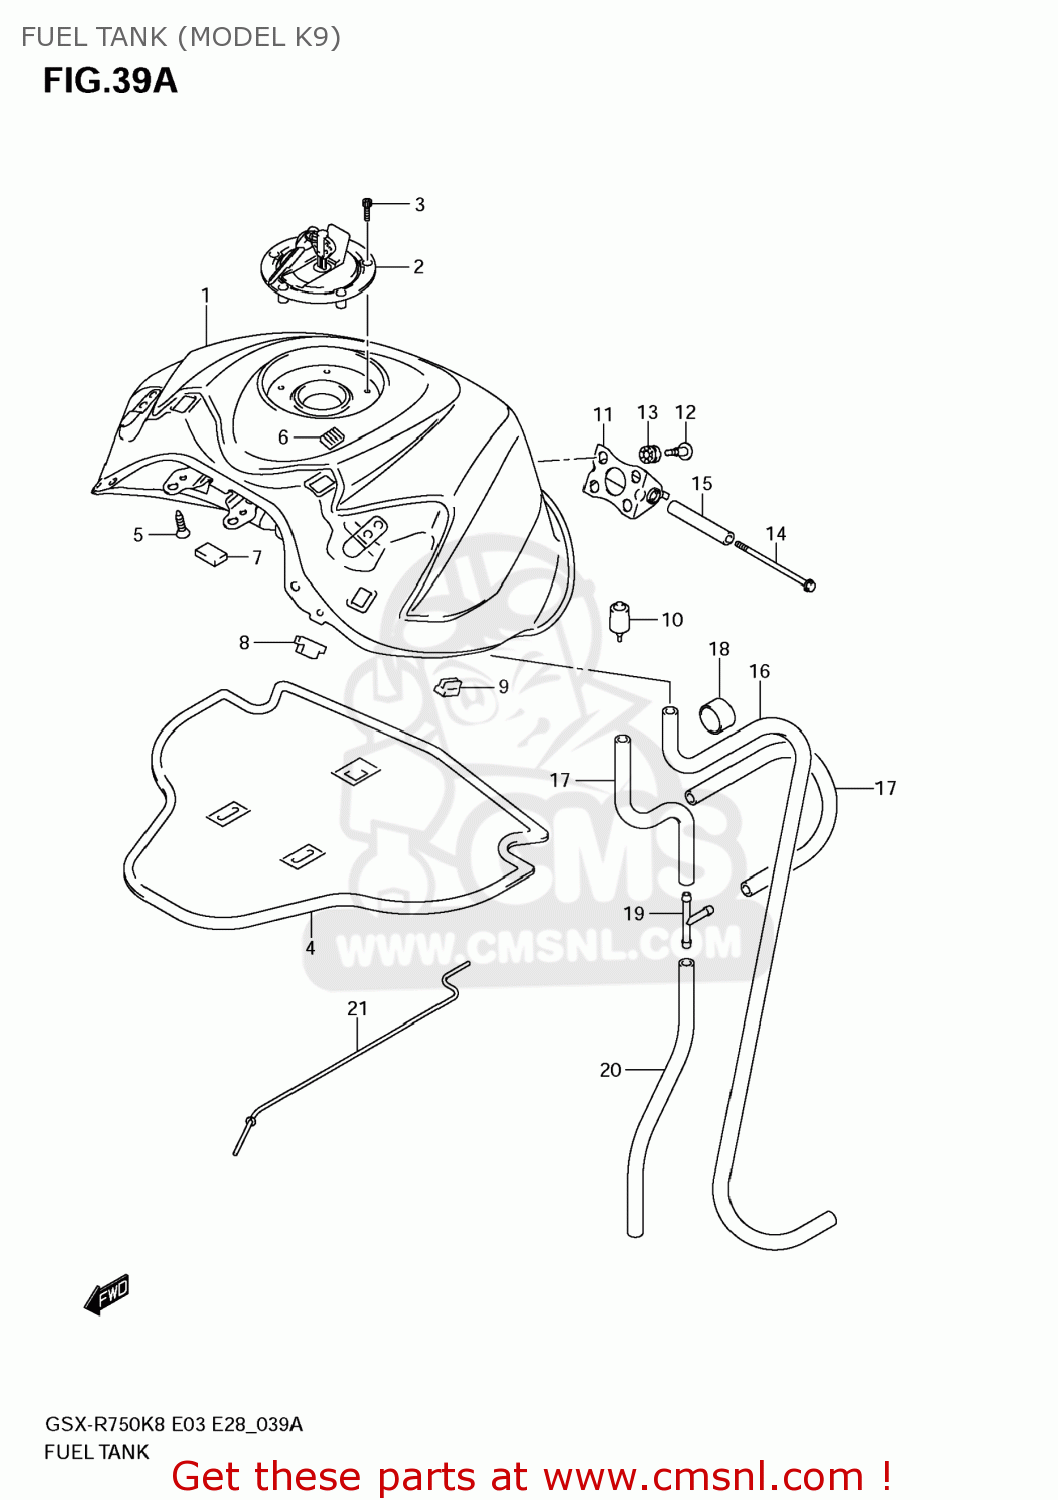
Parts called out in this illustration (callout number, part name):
1	TANK ASSY,FUEL
2	CAP SET,FUEL TANK
3	BOLT(5X20)
4	SHIELD,FUEL TANK HEAT
5	SCREW(6X10)
6	FASTENER
7	CUSHION
8	CUSHION,FUEL TANK SIDE
9	CUSHION,FUEL TANK COVER
10	CUSHION,FUEL TANK RR
11	BRACKET,FUEL TANK NO.1
12	SCREW,FUEL TANK RR BRACKET
13	CUSHION
14	BOLT(6X110)
15	SPACER,FUEL TANK RR
16	HOSE,TANK WATER DRAIN
17	HOSE,TANK BREA
18	HOSE(12X16X600)
19	JOINT,3 WAY
20	HOSE(5X8.2X2000)
21	STAY,FUEL TANK
